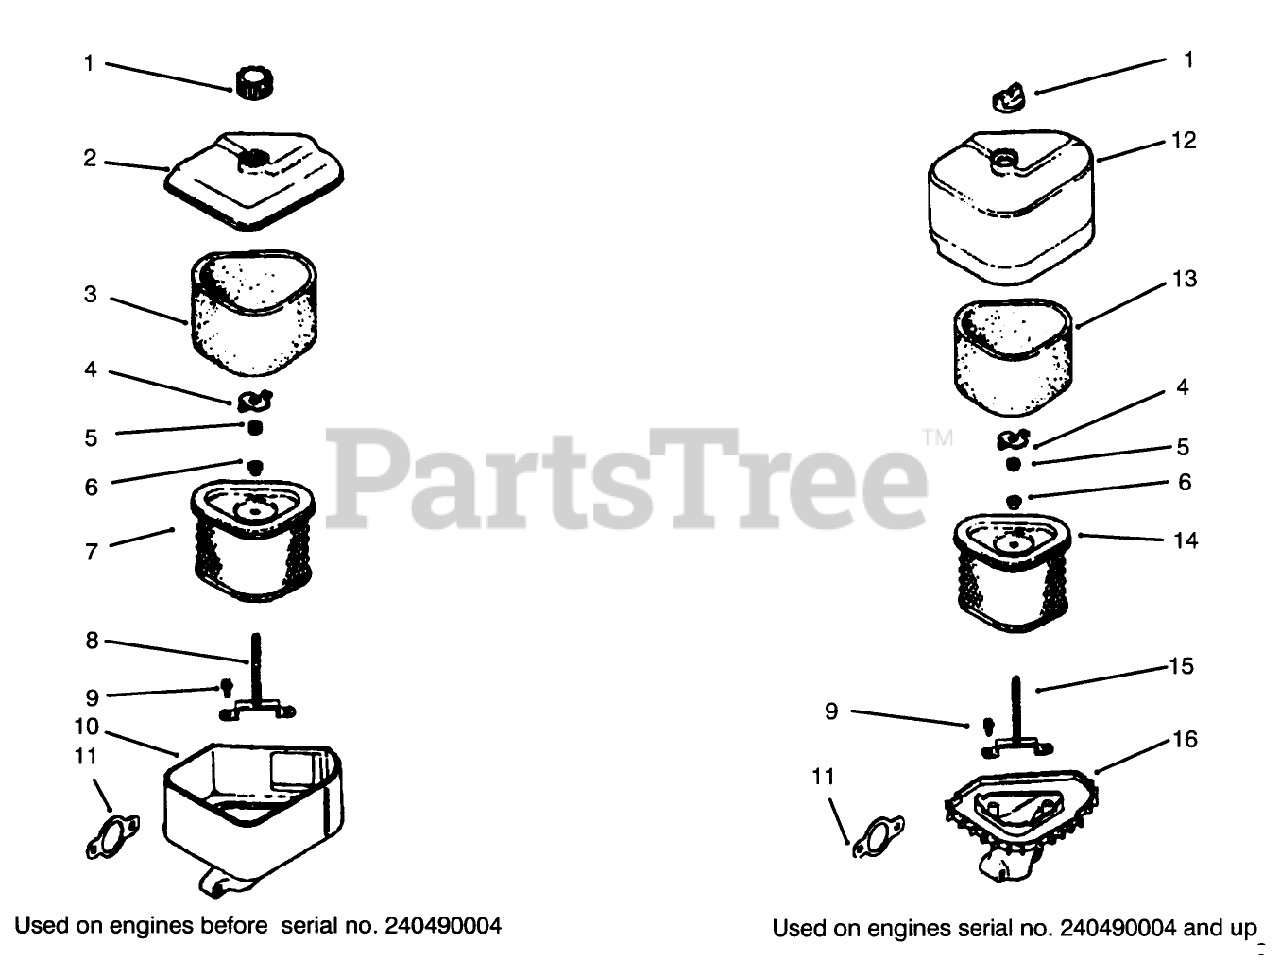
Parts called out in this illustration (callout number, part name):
1	Knob-Air Cleaner Cover (Only On: 72042, 72043, 72062, 72063)
2	Cover-Air Cleaner (Only On: 72042,72043,72062,72063)
3	Precleaner-Element (Only On: 72042,72043,72062,72063)
4	Nut-Wing
5	Washer
6	Grommet
7	Element-Air Cleaner (Only On: 72042, 72043, 72062, 72063)
8	Stud-Mounting Plate (Only On: 72042, 72063, 72062, 72043)
9	Screw-Mounting Plate (Only On: 72042, 72043, 72062, 72063)
10	Base-Air Cleaner (Only On: 72042, 72043, 72062, 72063)
11	Gasket-Air Cleaner (Only On: 72042, 72043, 72062, 72063)
12	Cover-Air Cleaner
13	Precleaner-Element
14	Element-Air Cleaner
15	Stud-Mounting Plate
16	Base-Air Cleaner
